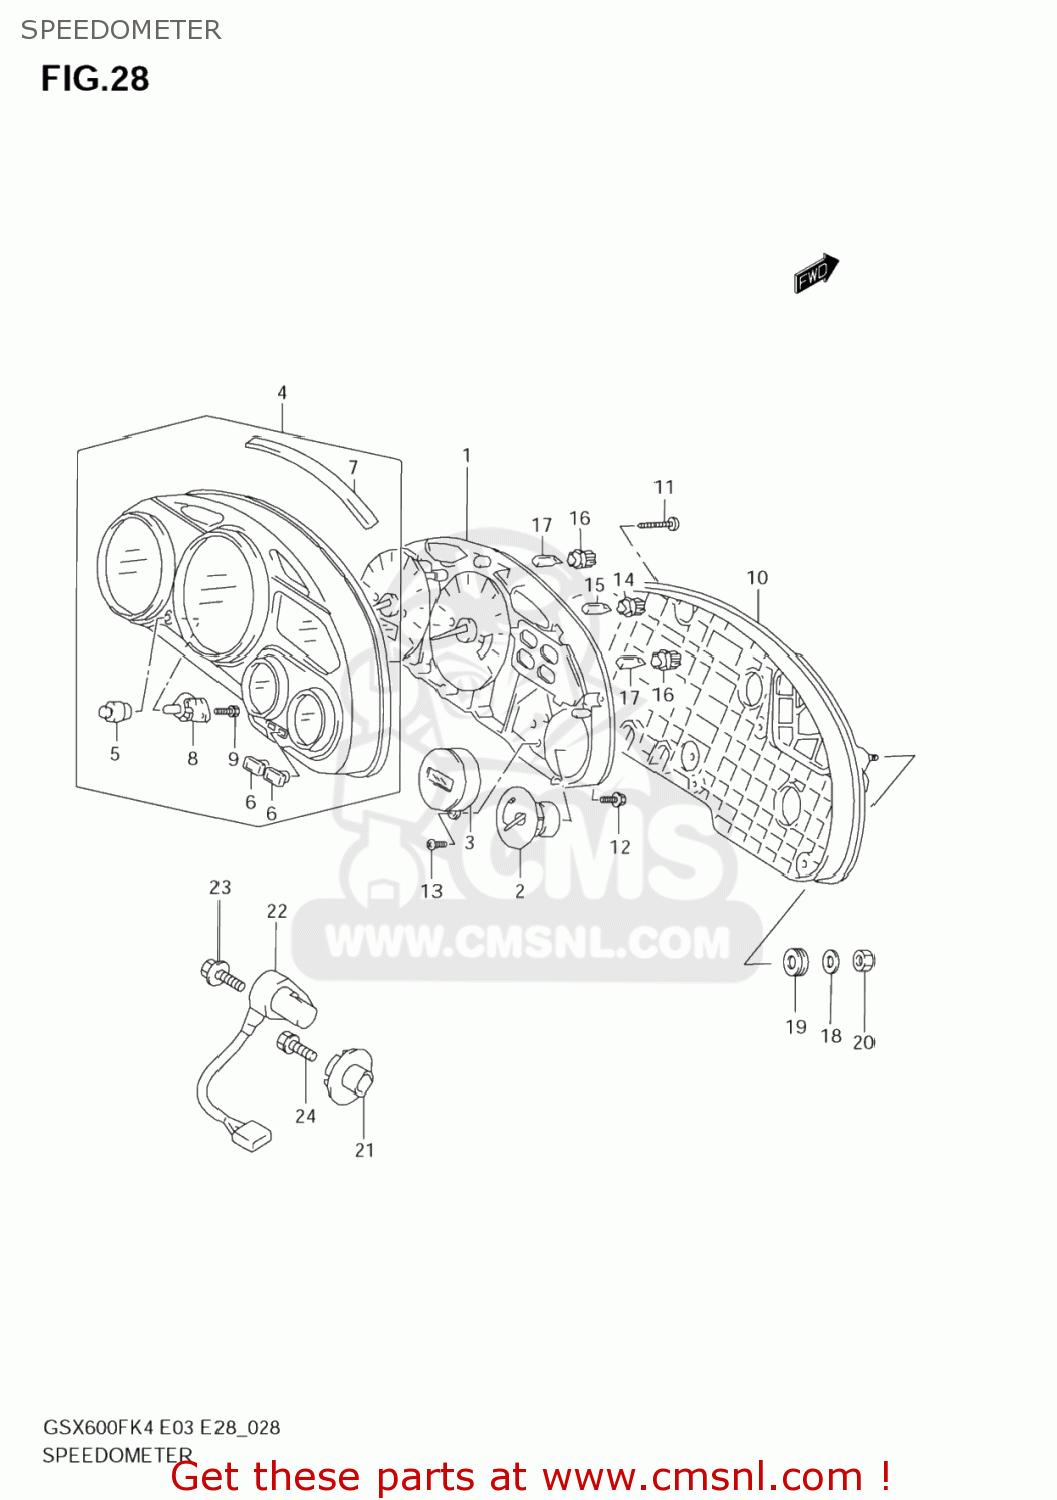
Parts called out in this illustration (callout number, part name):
1	SPEEDOMETER
2	FUEL,METER
3	CLOCK ASSY
4	VISOR ASSY
5	SWITCH,GUM
6	SWITCH,GUM
7	PACKING (NAS)
8	ATTACHMENT,SWITCH
9	SCREW(3X10)
10	CASE ASSY
11	SCREW
12	SCREW
13	SCREW
14	SOCKET(T:6.5)
15	BULB(12V1.7W,T6.5)
16	SOCKET
17	BULB(14V1.4W,T5)
18	WASHER(6.5X22X1.6)
19	CUSHION
20	NUT 6MM
21	ROTOR,SPEED
22	SENSOR,SPEED
23	BOLT
24	BOLT
